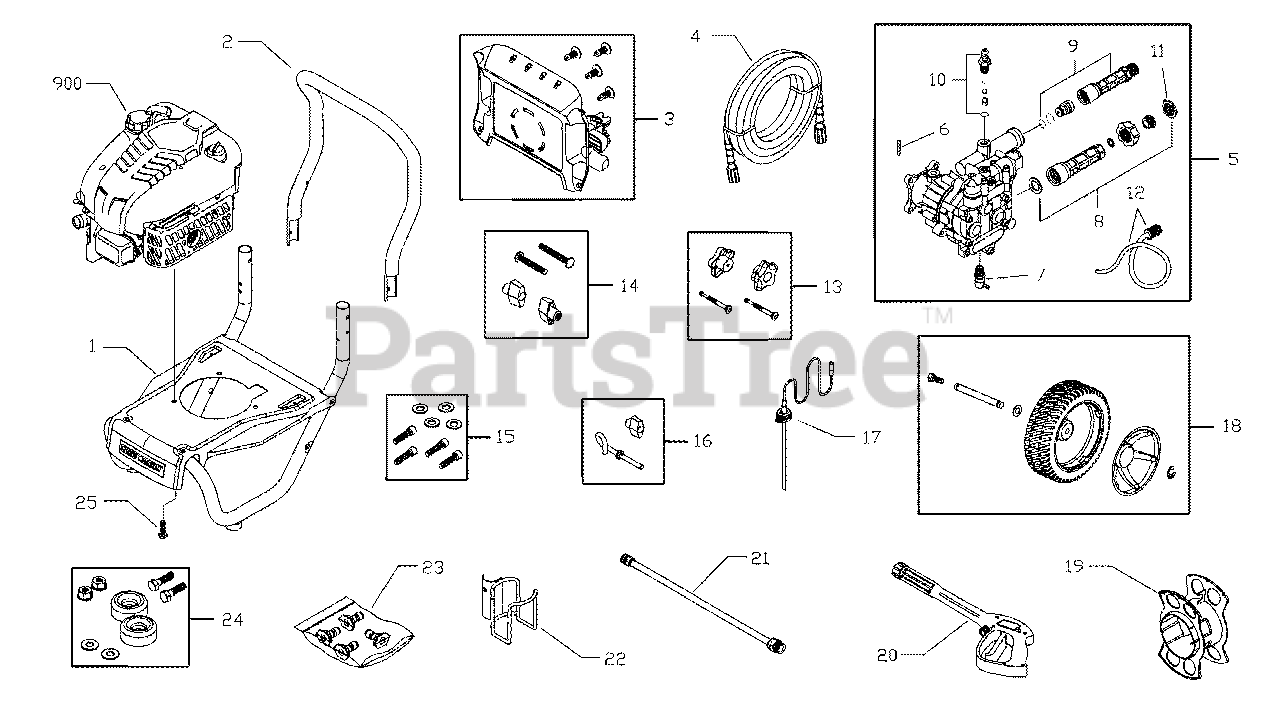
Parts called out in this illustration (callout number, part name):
1	BASE, w/Vib Mounts
2	HANDLE
3	KIT, Billboard w/Clips & Decals
4	HOSE
7	Valve, Thermal Relief
8	Kit, Water Inlet
10	Kit, Chemical Injection
12	Kit, Chemical Hose/Filter
15	KIT, Pump Mounting Hardware
16	KIT, Rope Guide
20	GUN
21	EXTENSION, QC
23	KIT, Spray Tips
24	KIT, Vibration Mount
25	HHS, Trilobular, 3/8-16 x 1-1/4
